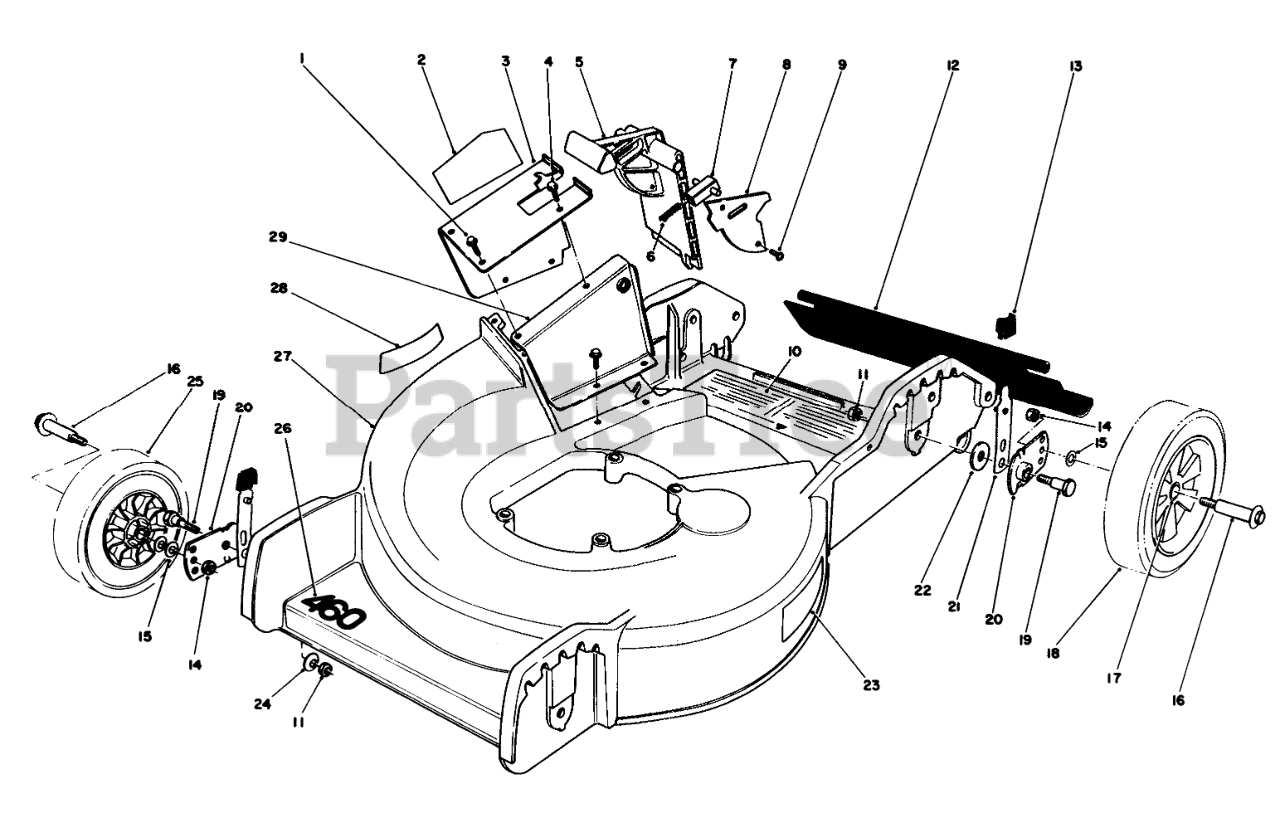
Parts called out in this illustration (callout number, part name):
1	SCREW
2	Decal-Danger
3	Tunnel-Outer
4	SCREW
5	Door Mulching
6	SPRING-COMPRESSION, LATCH
7	Door Latch
8	Cover Door
10	Danger-Decal
11	NUT-LOCK, NI
12	SHIELD - TRAILING
13	KNOB-ARM
14	Nut
15	WASHER
16	BOLT-WHEEL
17	BUSHING
18	Wheel & Tire Assembly (Incl. Ref. #17)
19	5/16-18 PIVOT SCREW
20	PIVOT ARM ASSY
21	SPRING ARM ASM
22	PIVOT WASHER
23	Decal-Step
24	WASHER-BELLEVILLE
25	Wheel & Tire Assembly (Inc. Ref. #17)
26	Decal-460
27	HSG & CARTON
28	STEP PAD DECAL
29	Tunnel-Inner
